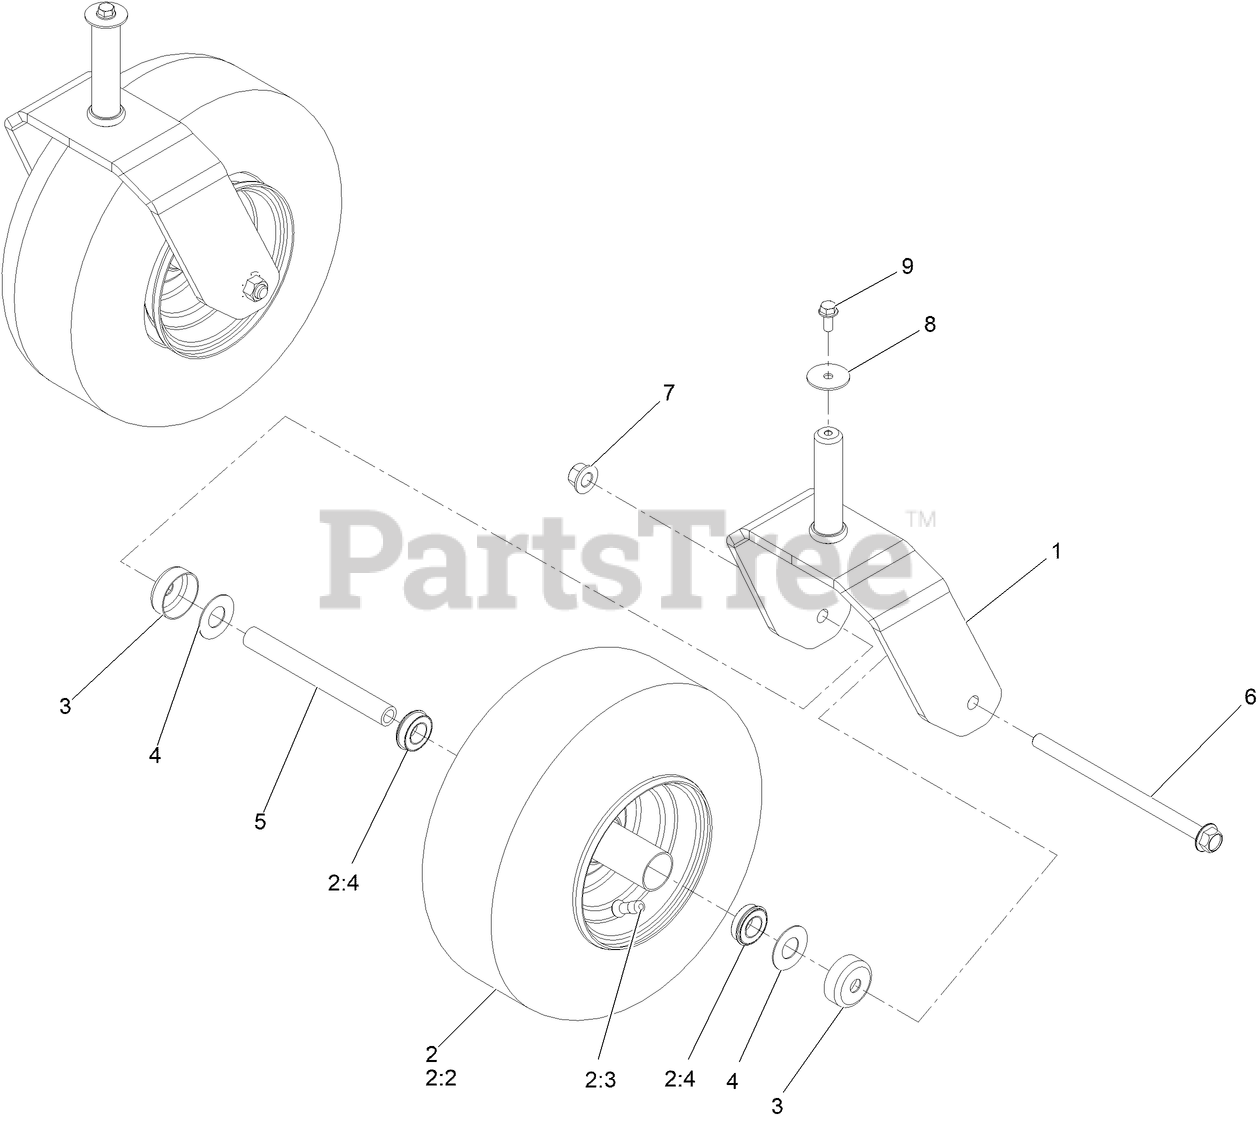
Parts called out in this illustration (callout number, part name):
2	TIRE AND WHEEL ASM
2:3	Stem-Valve
2:4	BEARING
3	GUARD-SEAL
5	SPANNER-WHEEL
6	SCREW-HHF
7	Nut-Lock 1/2-13
8	WASHER-FLAT
9	SCREW-HHF
